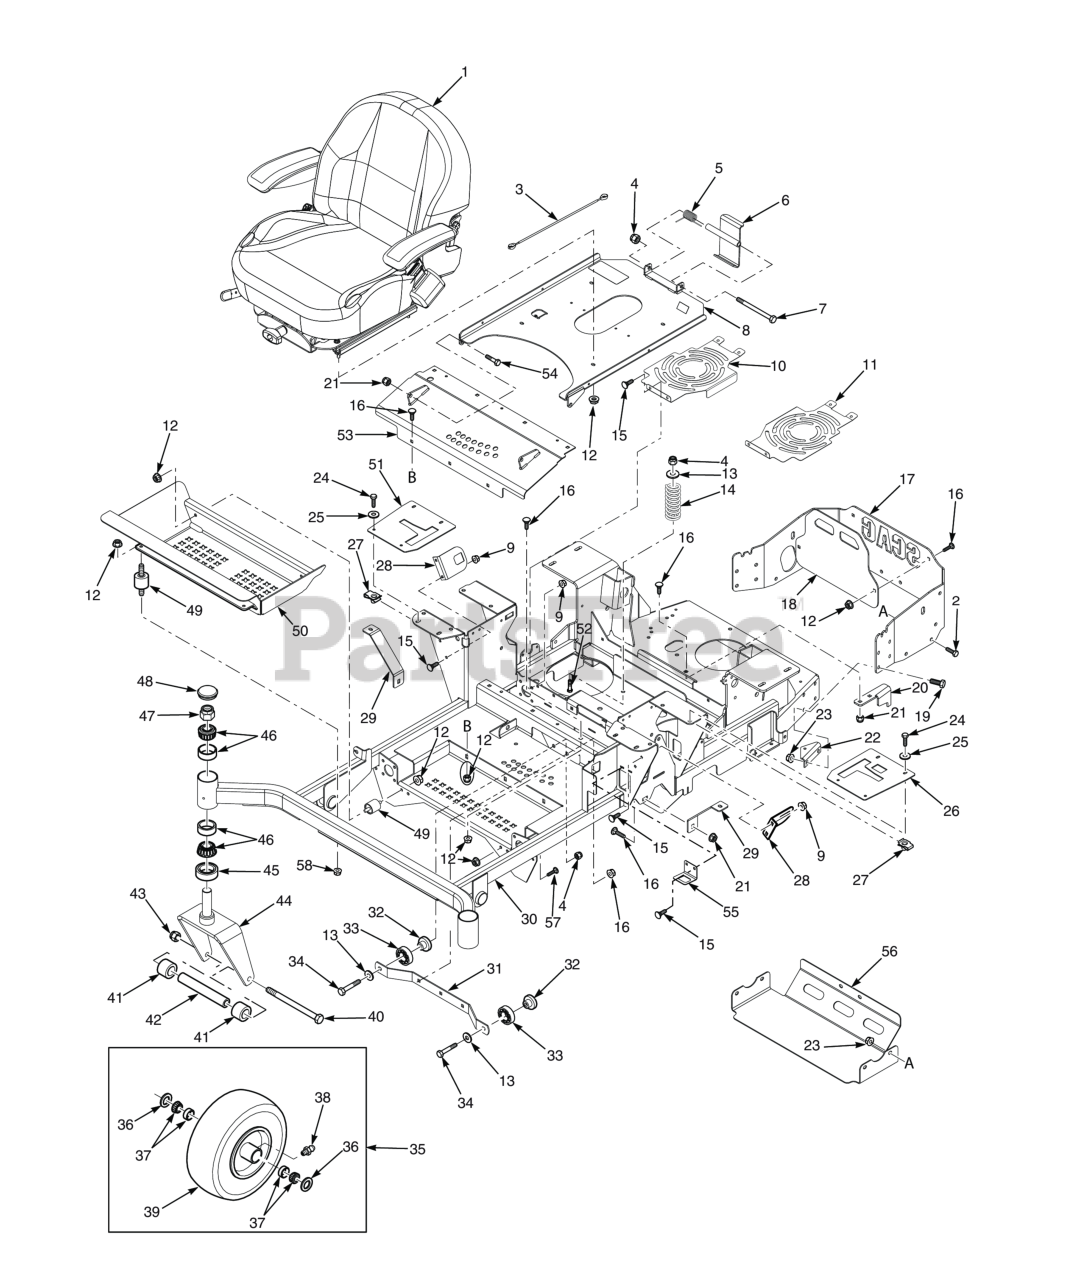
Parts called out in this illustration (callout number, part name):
1	Seat Assembly
2	Capscrew, 3/8-16 x 1.0" Serrated Flange Hex Hd
3	Cable, Seat Stop
4	HEX NUT, ELASTIC STOP LOCK, 3/8-16
5	Spring, Seat Latch
6	Weldment, Seat Latch
7	Bolt, 3/8-16 x 6.00" Hex Head
8	Seat Plate Weldment
9	NUT, 1/4-20 SERRATED FLANGE HEX HEAD
10	Fan Cover, RH
11	Fan Cover, LH
12	Nut, Serrated Flange 5/16-18 (Right Front Engine Mounting, Briggs and Kohler Only)
13	Flatwasher, 3/8" Special (.391 x .938 x .105)
14	Spring, Seat
15	Bolt, Carriage 1/4-20 x 1/2"
15	SERR. FLG. HEX HEAD CAPSCREW, 5/16-18 X 3/4
16	Bolt, 5/16-18 x .75 RHSN Carriage
16	Bolt, Heax Head 5/16-18 x 1" (48V / 52V)
17	Bumper, (Black)
18	Guard, Engine, (Scag Gold)
19	Bolt, Hex Head, 3/8-16 x 1 Gr. 5
20	Bracket, Anti-Rotation
21	HEX NUT, ELASTIC STOP LOCK, 3/8-16
22	Bracket, Dump Mounting
23	NUT, 3/8-16 SERRATED FLANGE HEX HEAD
24	CAP SCREW, 1/4-20 X 1" SERRATED FLANGE HEX
25	Flatwasher, 1/4" (.312 x .750 x .065")
26	Control Plate w/Decal, LH (Black)
27	Bolt, Hex Head 3/8-16 x 1"
28	Bracket, Switch Mount
29	Bracket, Tank Mount, SFZ61
30	Mainframe Assy., w/Decals (Black)- SPZ61
31	Support, Deck Guide
32	Spacer, Bearing
33	Bearing
34	Capscrew, Hex Head 3/8-16 x 2-1/2"
35	Wheel Assembly, (Black)
36	Roller Bearing, Short
37	Bearing, Tapered Roller
38	Fitting, Grease
39	Tire, 13 x 6.50 4-Ply (61A, 72A)
39	Rim, (Black)
40	Bolt, Hex Head 1/2-13 x 9-1/2" (61V & 72A/VS)
41	Spacer, Caster Wheel
42	Sleeve, Caster Wheel (61V, 72A/VS)
43	HEX LOCKNUT, ELASTIC STOP, 1/2-13
44	Yoke Weldment, (Black))
45	Seal, 2.00" O.D. x 1.625" Bore
46	BEARING & CUP, TAPERED SPINDLE
47	Nut, Hex Elastic Stop 1.0"-14
48	Cap, Grease
49	Rubber Isolator
50	Footplate Weldment, (Black) - SPZ61
51	Control Plate w/Decal, RH (Black)
52	SHORT SQ. NECK CARRIAGE BOLT, 3/8-16 X 1-1/4"
53	Deck Lift Cover w/Decal, (Scag Gold Logo) - SPZ61
54	Capscrew, 3/8-16 x 1.0" Serrated Flange Hex Hd
55	Switch Bracket
56	Heat Shield, (Scag Gold)
56	Heat Shield
57	Bolt, Heax Head 5/16-18 x 1" (48V / 52V)
58	Nut, Flange Head Elastic Stop 5/16-18
